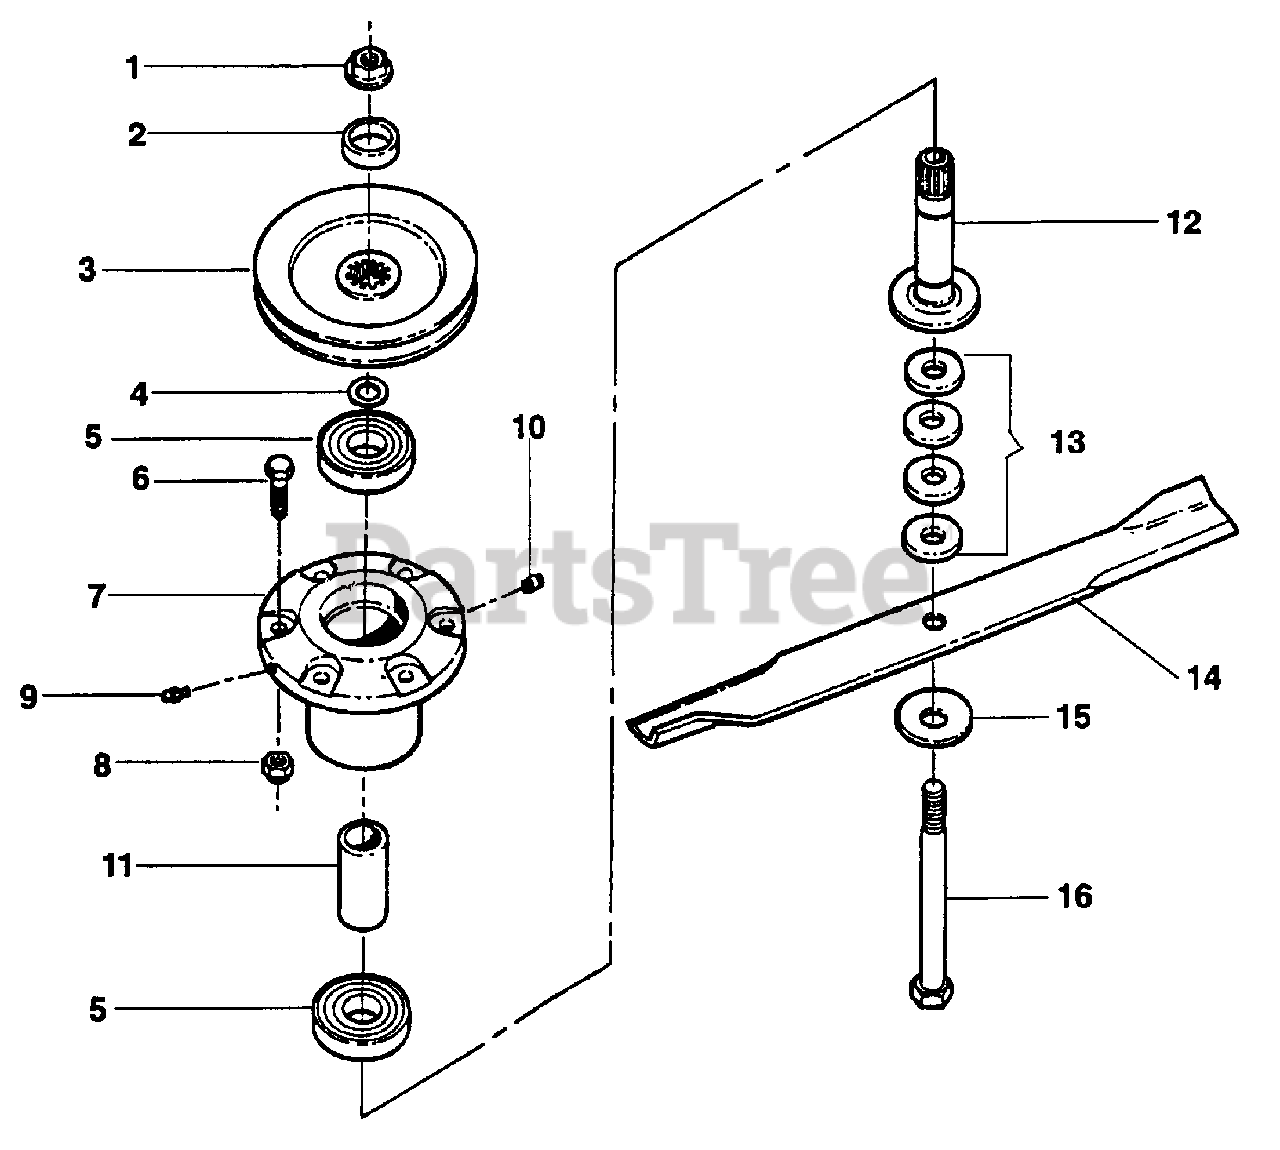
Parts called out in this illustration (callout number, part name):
1	NUT, 5/8-18 Hex Flange Lock, Grade 5
2	WASHER, Spindle
3	PULLEY, 5 3/4" O.D.
4	SNAP-RING, Spindle Shaft
5	BEARING, Sealed
6	BOLT, 3/8-16 x 1 1/4" Rib Necked
7	HOUSING, Cutter
8	NUT, 3/8-16 HEX NYLON LOCK
9	LUBE FITTING, 1/4-28 Thread Forming
10	VENT, Spindle
11	SPACER, Bearing
12	SHAFT, Spindle
13	SPACER, Blade
14	BLADE, 25 Inch
15	WASHER, Beveled
16	BOLT, 5/8-18 x 7 1/2" Hex Head Cap, Grade 5
